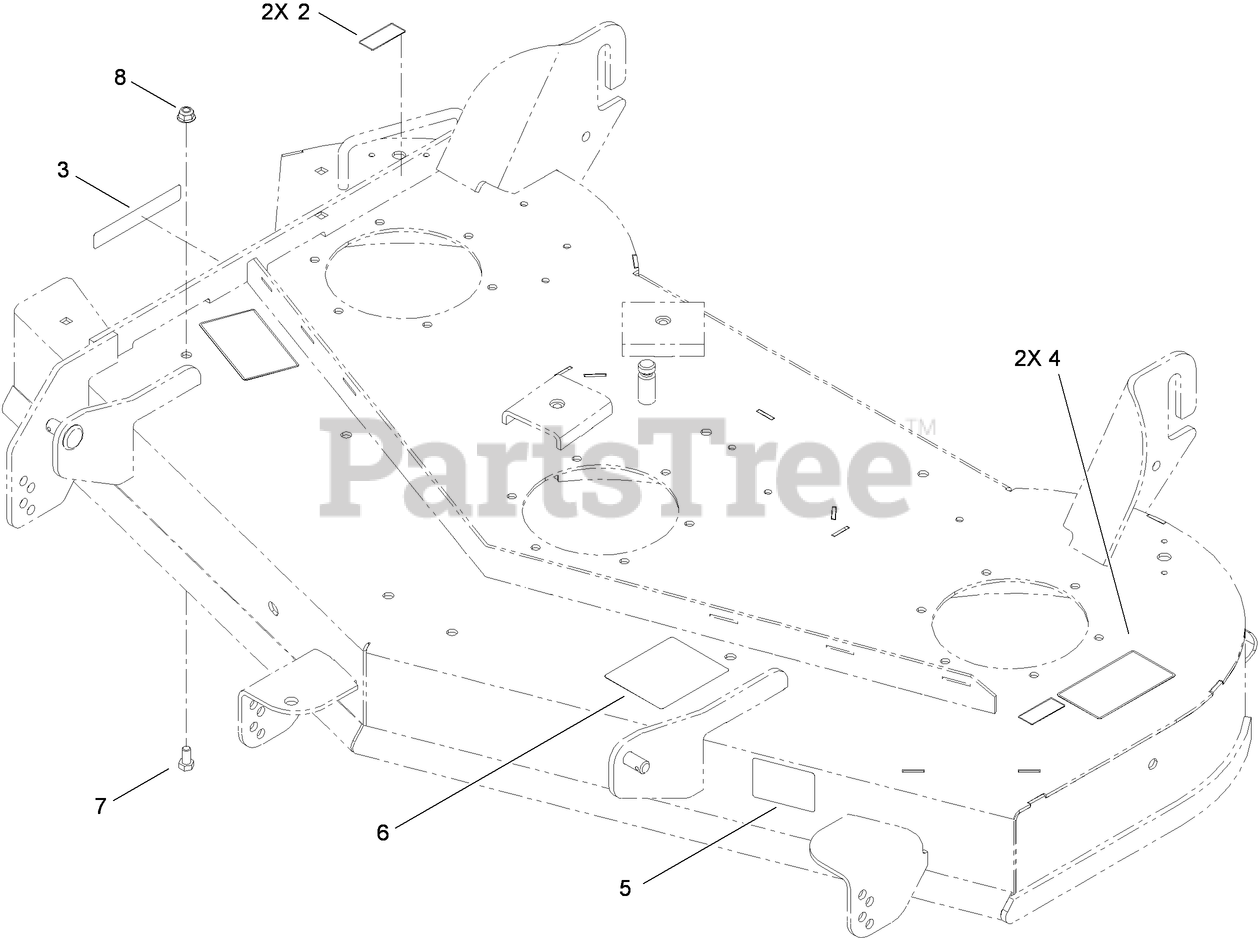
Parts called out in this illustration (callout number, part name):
2	DECAL-DANGER
3	DECAL-DANGER
4	DECAL-DANGER
5	DECAL-SCALP, ANTI
6	DECAL-ROUTING, BELT
7	SCREW-HH
8	NUT-HF, NI
